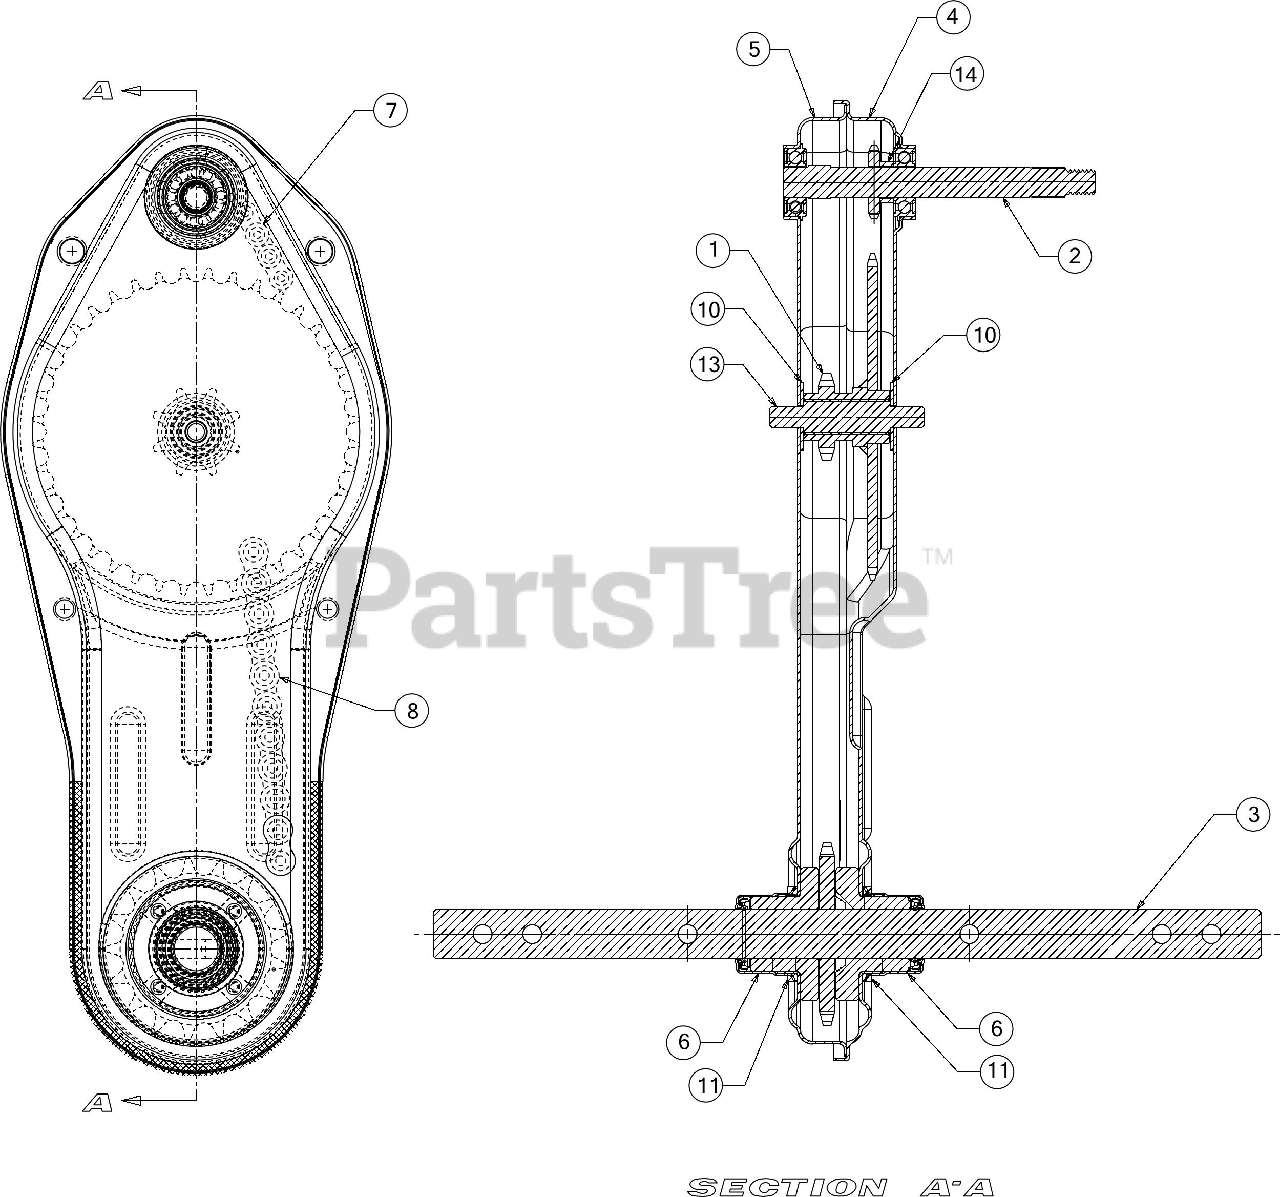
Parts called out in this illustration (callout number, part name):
7	#420 CHAIN 1/2 PITCH
8	#50 CHAIN 5/8 PITCH
10	FLAT WASHER
